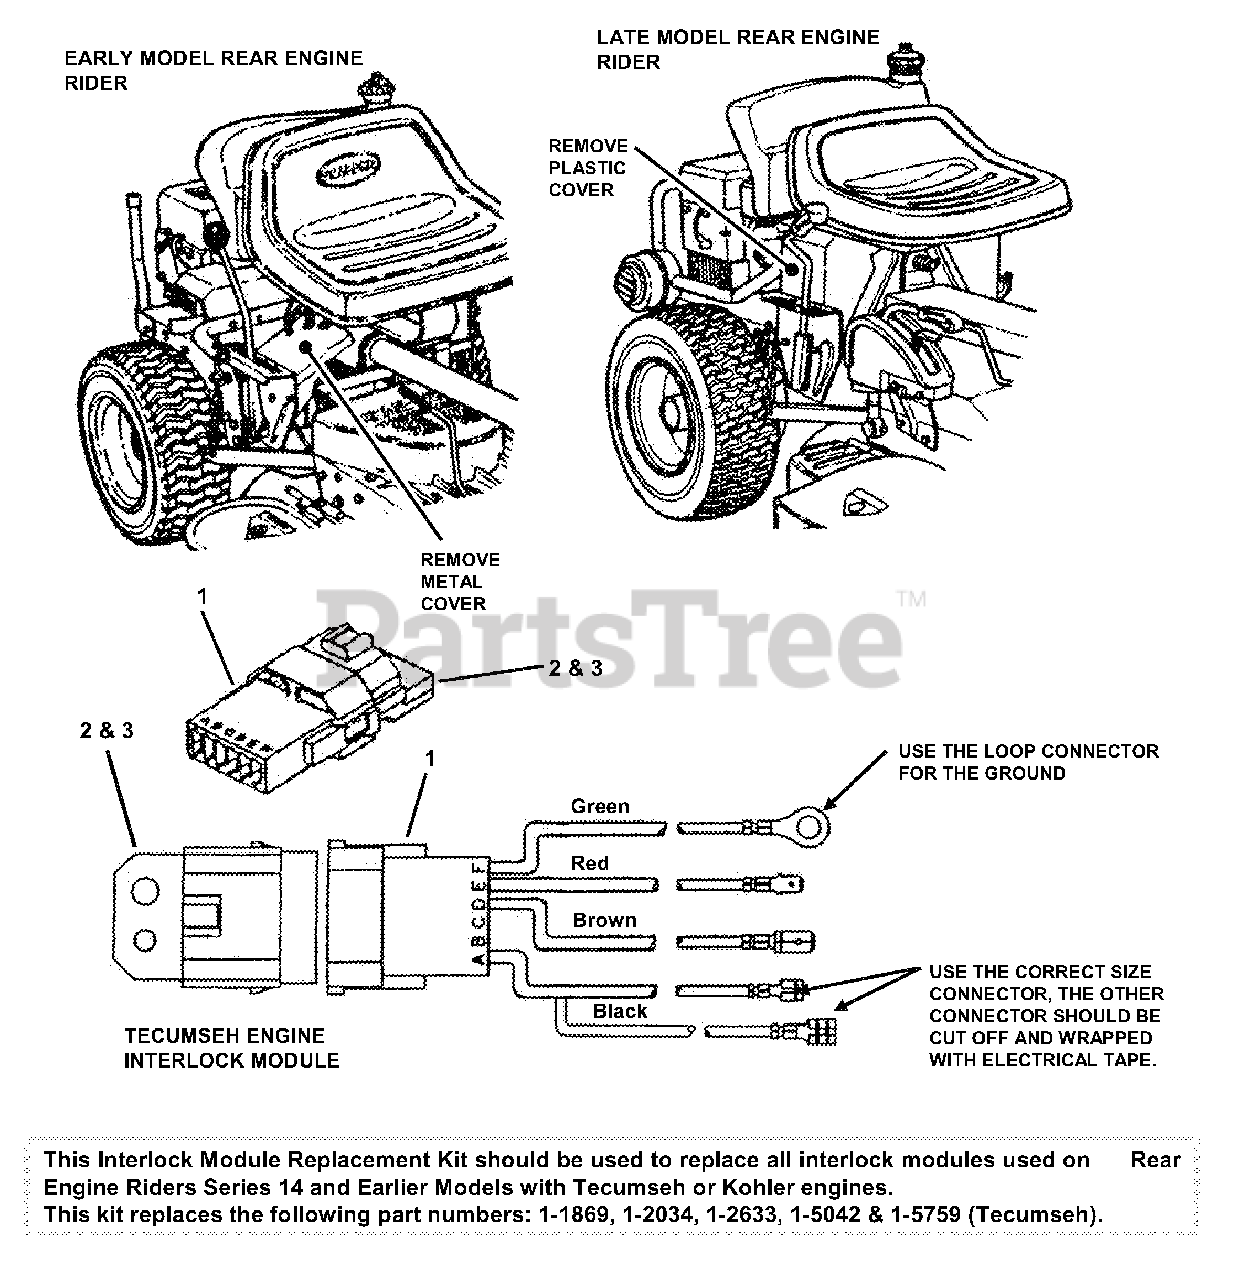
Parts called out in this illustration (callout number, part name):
1	HARNESS, Tecumseh RER Module
2	INTERLOCK, Tecumseh (0901T) & series 14 and lower Kohlers
3	INTERLOCK, Tecumseh (0901T) & series 14 and lower Kohlers
